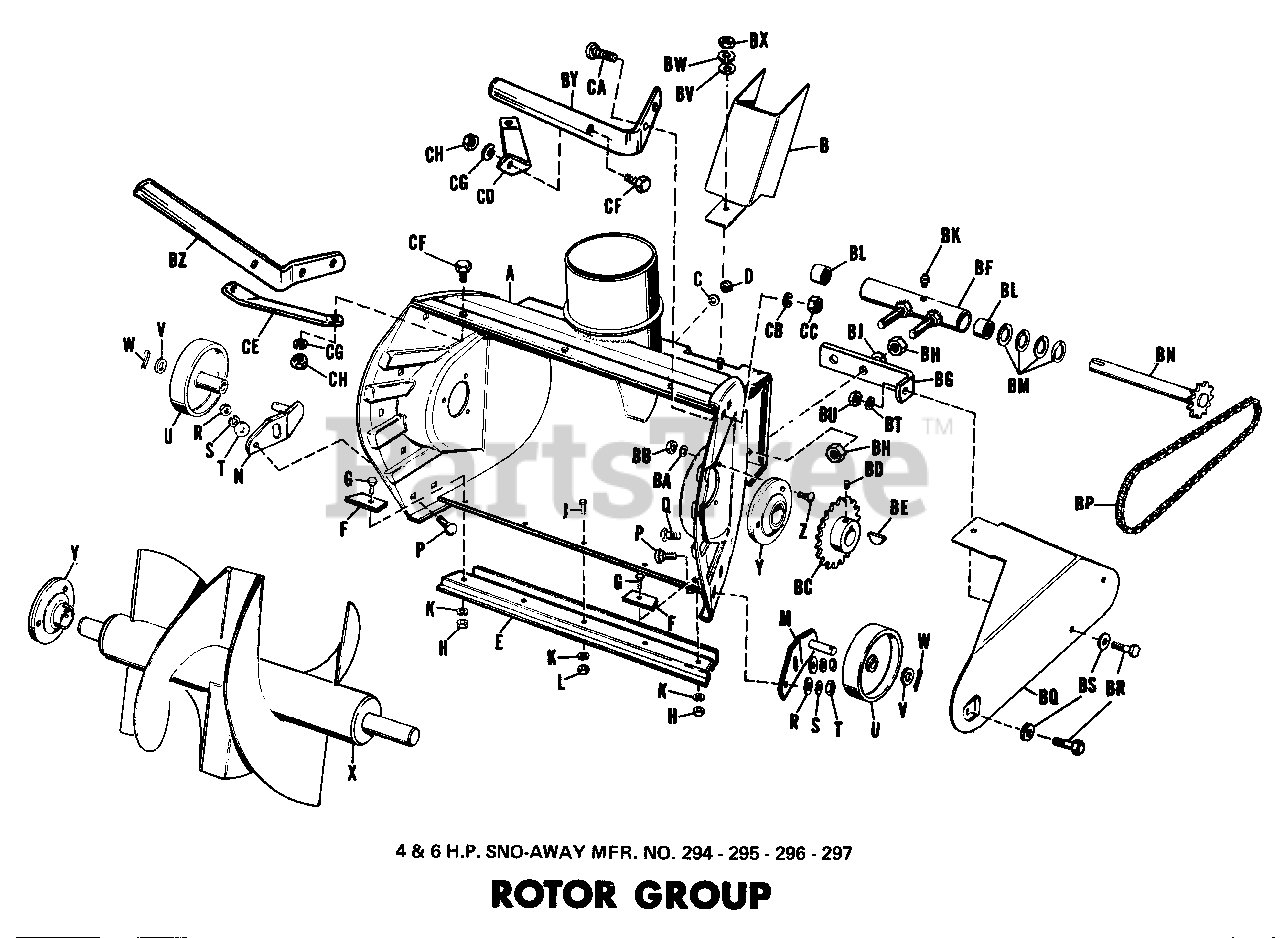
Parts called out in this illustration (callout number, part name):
A	Body Assembly
B	Belt Cover Cover
C	Lockwasher 3/8"
D	Hex Nut, Full 3/8"-16
E	Scraper Body
F	Clamp, Scraper
G	Hex. Capscrew 5/16" x 7/8" lg.
H	Hex Nut, Full, Lock, 5/16"
J	Hex Capscrew 1/4"-20 x 5/8" lg.
K	Lock Washer 1/4"
L	Hex Nut, Full, 1/4"-20
M	Roller Bracket Assembly LH
N	Roller Bracket Assembly RH
P	Carriage Bolt
Q	Hex Capscrew 3/8"-16 x 7/8" lg.
R	Plain Washer 3/8"
S	Look Washer 3/8"
T	Hex Nut, Full, 3/8"-16
U	Roll Assembly
W	Cotter Pin, 1/8" x 1-1/4" long
X	Rotor Assembly
Y	Ball Bearing
Z	Hex Capscrew, 5/16" x 3/4" lg.
BA	Lock Washer 5/16"
BB	Hex Nut, Full, 5/16"-18
BC	Rotor Sprocket
BD	Set Screw Cup Pt., 5/16"-18 x 5/16"
BF	Housing Assembly Bearing
BG	Chain guard Bracket
BH	Hex Nut, Full, 1/2"-13
BJ	Washer Plain, 1/2"
BK	Fitting, Grease
BL	Needle Bearing
BN	Shaft Assembly
BP	Rotor Chain
BQ	Chain Guard
BR	Hex Capscrew 5/16"-18 x 5/8" lg.
BS	Plain Washer 5/16"
BT	Lock Washer 5/16"
BU	Hex Nut, Full, 5/16"-18
BV	Plain Washer 3/8"
BW	Lock Washer 3/8"
BX	Hex Nut, Full, 3/8"-16
